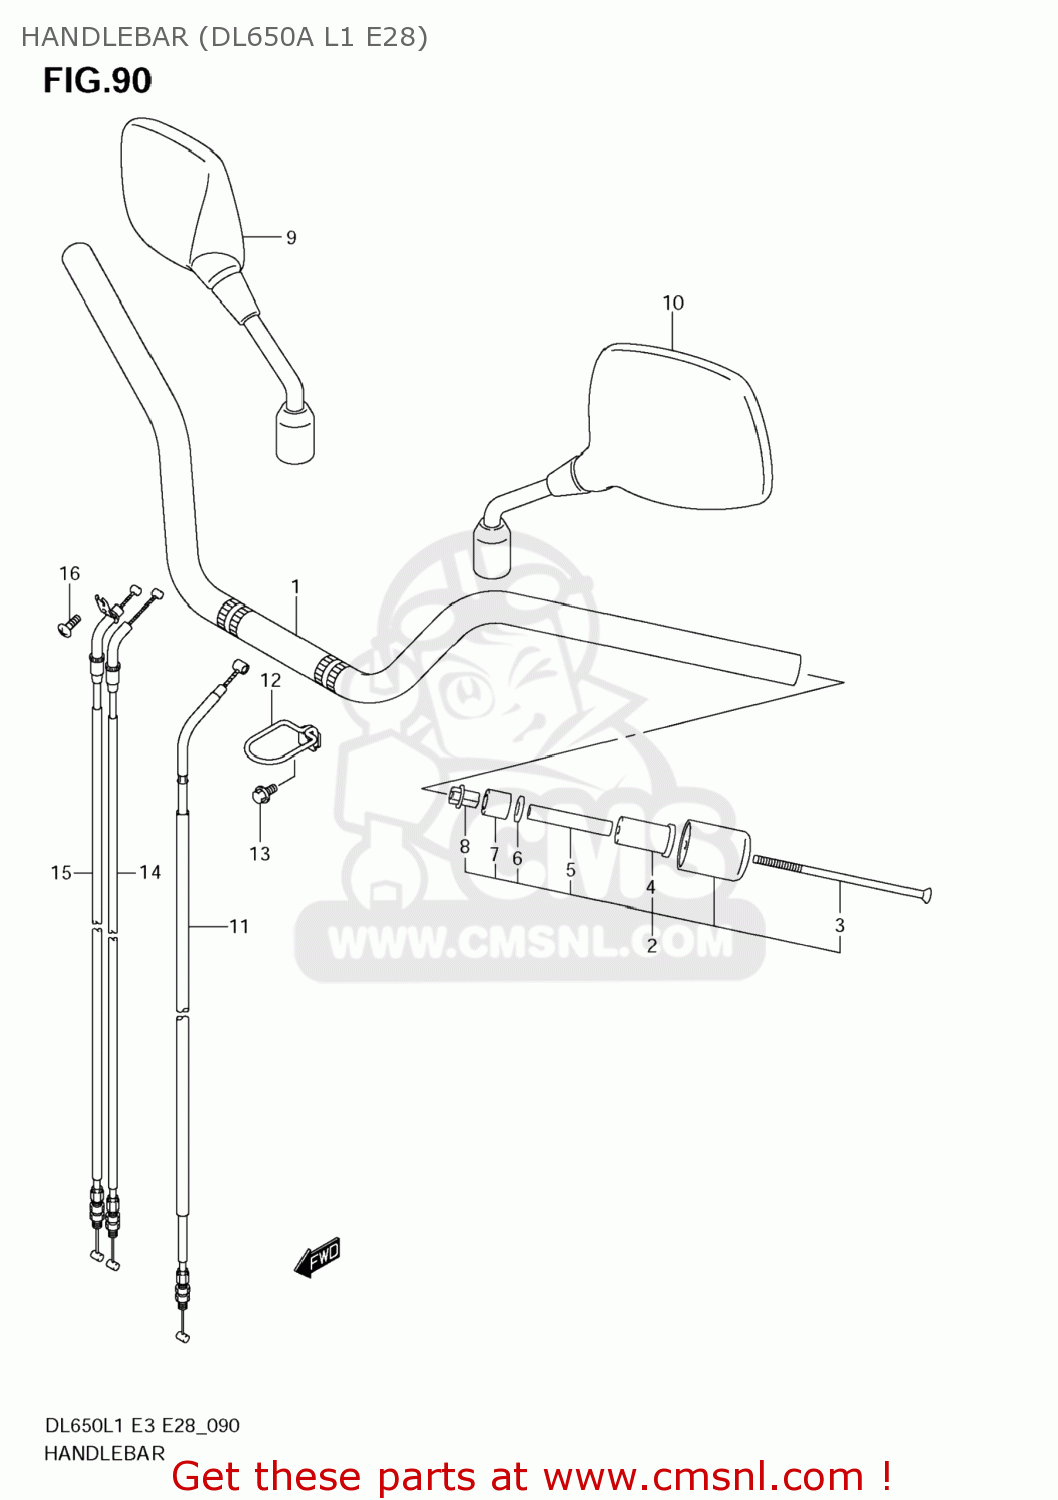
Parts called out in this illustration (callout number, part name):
1	HANDLEBAR
2	BALANCER SET,HANDLEBAR
3	SCREW(6X110)
4	EXPANDER
5	SPACER,EXPANDER
6	WASHER(6.5X16X4)
7	EXPANDER,HANDLE BALANCER
8	NUT,HANDLE BALANCER
9	MIRROR ASSY,RE
10	MIRROR ASSY,LH
11	CABLE ASSY,CLUTCH
12	GUIDE,CLUTCH CABLE
13	BOLT
14	CABLE ASSY,THROTTLE NO.1
15	CABLE ASSY,THROTTLE NO.2
16	SCREW(5X10)
